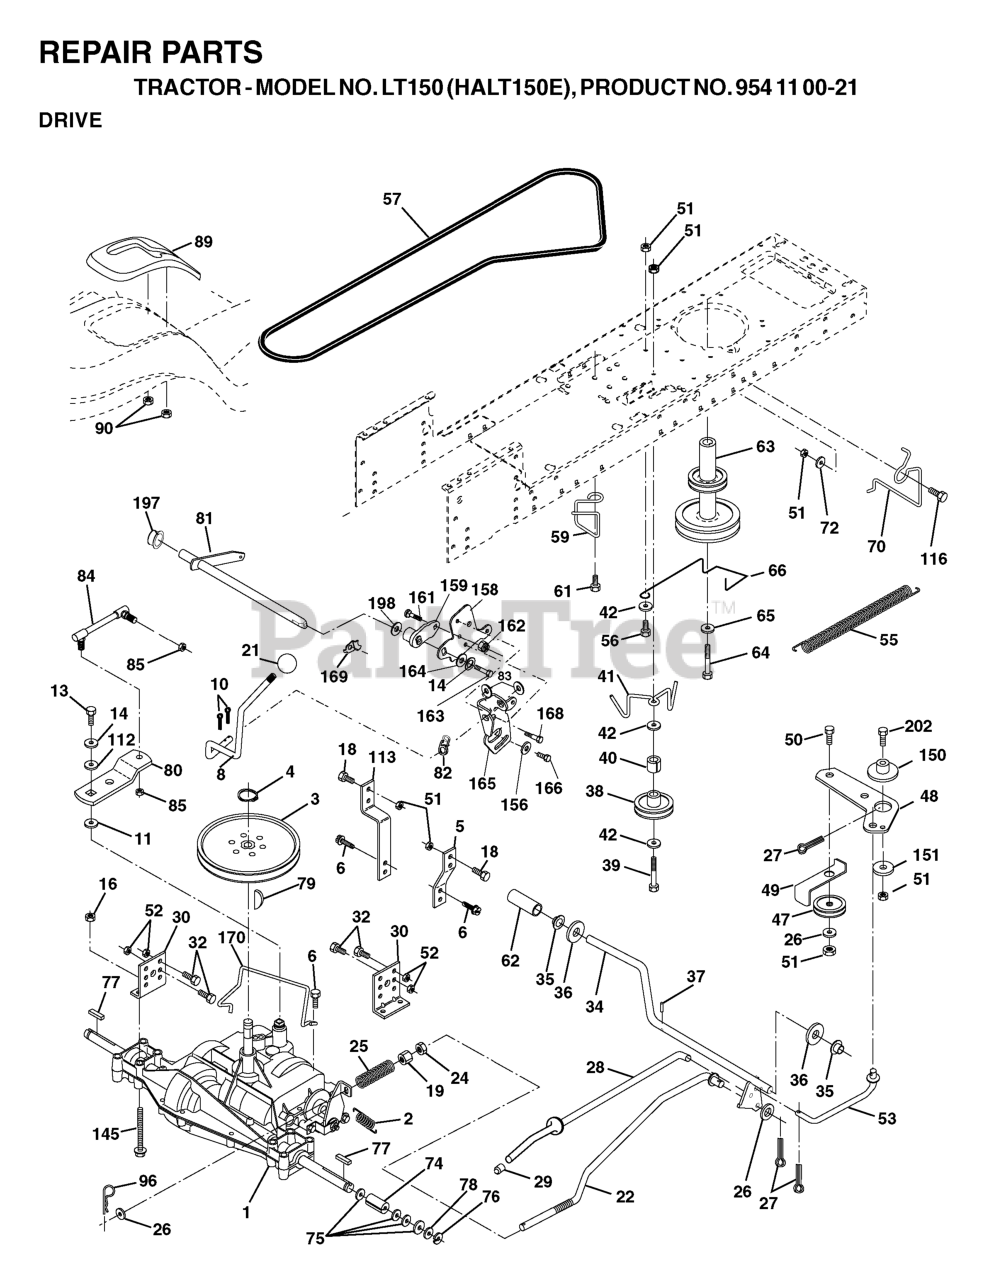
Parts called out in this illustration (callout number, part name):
2	SPRING,BRAKE RETURN
3	PULLEY TRANS
4	RETAINING RING LT
5	STRAP TORQUE
6	SCREW 5/16"
8	ROD SHIFT FENDER ADJUST STLT
10	PIN COTTER
11	WASH-SHFT PLT LT
13	BOLT 1/4-28X3/4
14	LOCKWASHER
16	NUT.71038.31-18.HEX.NYLOCK
19	NUT
21	KNOB.DELUXE.(PISTOL.GRIP).BLAC
24	NUT
25	SPRING ROD LT
26	WASHER
27	COTTER PIN
28	ROD BRAKE PARK LT
29	PLUNGER CAP
30	BRKT, TRNSXLE MNT 20"
32	BOLT
34	SHAFT, FOOT PEDAL
35	BEARING.NYLON
37	DRIVE PIN
38	FLAT IDLER PULLEY
41	KEEPER.BELT.IDLER.FLAT
42	WASHER
47	IDLER PULLEY
48	BELLCRANK, CLUTCH
49	RETAIN BELT
50	BOLT
52	LOCKNUT
53	LINK, CLUTCH LT
55	SPRING, RETURN LT
57	V-BELT
59	KEEPER, BELT CENTER
61	SCREW 3/8-16X3/4
62	COVER, PEDAL (1 2)
63	PULLEY.ENG.CL.MECH.SLVR.LT/YT
64	BOLT
65	LOCKWASHER
66	KEEPER BELT ENGINE
70	KEEPER BELT ENG
72	WASHER
74	SPACER AXLE
77	SQUARE KEY
79	KEY STD (1373) DANA
81	SHAFT ASM CROSS TAPERED PMST/2
82	SHIFT SPRING
83	WASHER
84	LINK.TRANSAXLE.PMST/DANA.20"
85	NUT LOCK CENTER 1/4 -28 FNTHD
90	NUT.PUSH.3/16
96	RETAINER M
113	STRAP TORQUE LH LT
116	BOLT
150	BUSHING.BELLCRANK.GRD.DR
151	WASHER 12/32X2X10GA
156	WASHER.SRRTD.5/16
158	BRACKET
159	HUB
161	BOLT
162	NUT.CROWNLOCK.1/4
164	Washer 5/8 x .281 x 10 Ga.
165	RP BRACKET
168	BOLT.SHOULDER.5/16-18X
169	PLATE.FASTENING.CROSS.SHAFT
170	KEEPER BELT TRANSAXLE GEAR
197	NYLINER SNAP 5/8" ID
198	WASHER.NYL.7/8IDX.105"HYD CR
202	BOLT.3/8-16X1.50
204	SCREW 5/16-18X1
